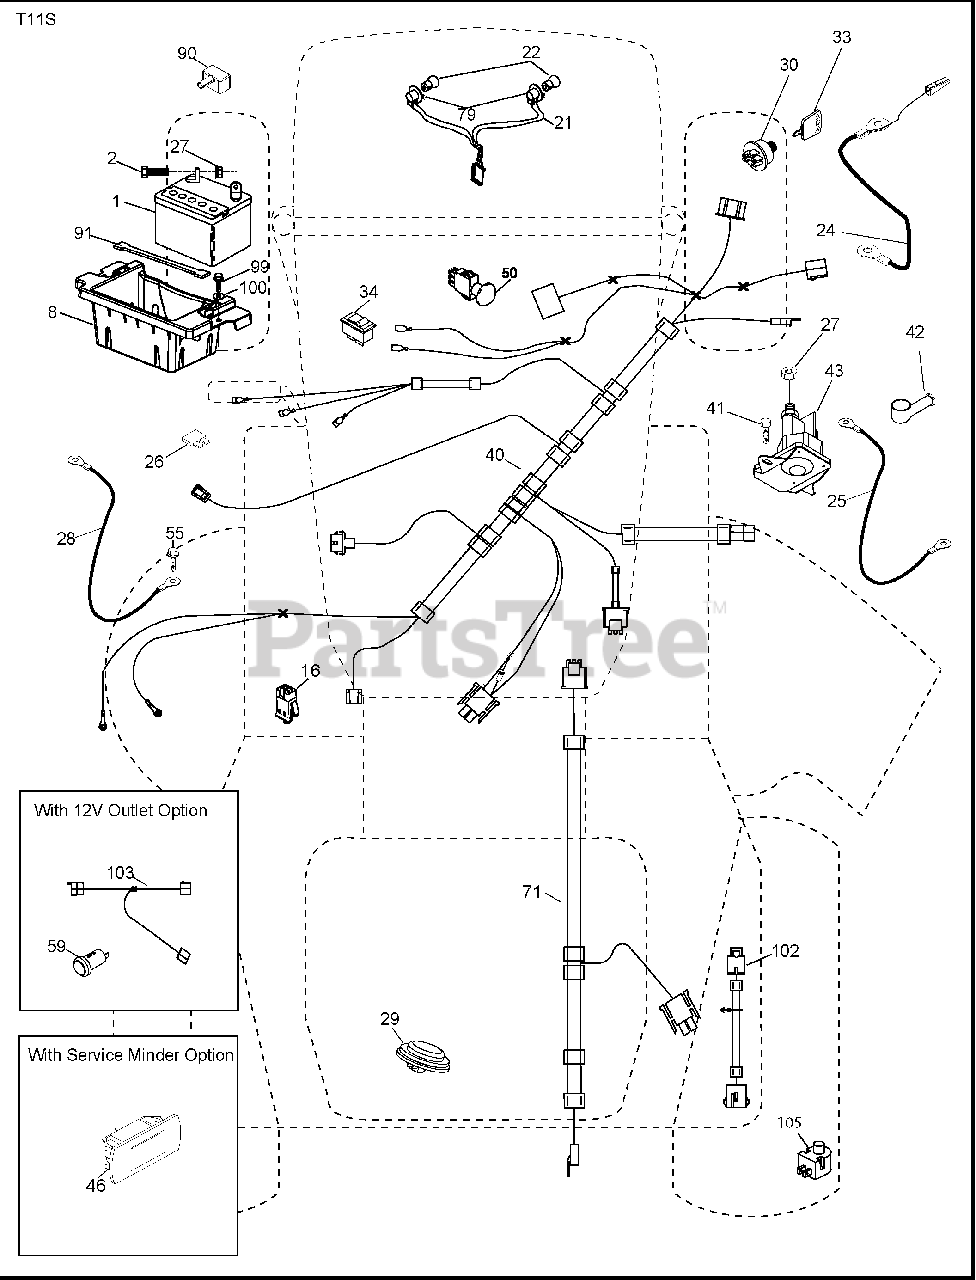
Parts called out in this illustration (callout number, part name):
1	Battery
2	Bolt Hex Head 1/4-20 x 3/4
8	Box Battery
16	Switch Interlock Push-In
21	Harness Socket Light w/4152J
22	Bulb Light
24	Cable Battery
25	Cable Starter
26	Fuse
27	Nut Keps. Hex 1/4-20 unc
28	Cable, Ground
29	Switch, Seat
30	Switch, Ign.
33	Key/Chain
34	Switch Light/Reset
40	Harness Ign. Dash
41	Screw Thd. Cut 1/4-20 x 1/2
42	Cover, Terminal
43	Solenoid
46	Gauge Hourmeter
50	Switch PTO
55	Screw Thdrol. 5/16-18 x 3/4 TYTT
71	Harness Chassis
79	Socket Asm. Bulb Twistlock
90	Cover Terminal Battery
91	Strap Battery Mount Front
99	Screw Hex Wsh. Thdrol. 1/4-20 x 3/4
100	Washer 9/32 x 7/8 x 16 Ga.
102	Harness Pigtail K46 TEX ROS
105	Switch Reverse TT Pedal Control
